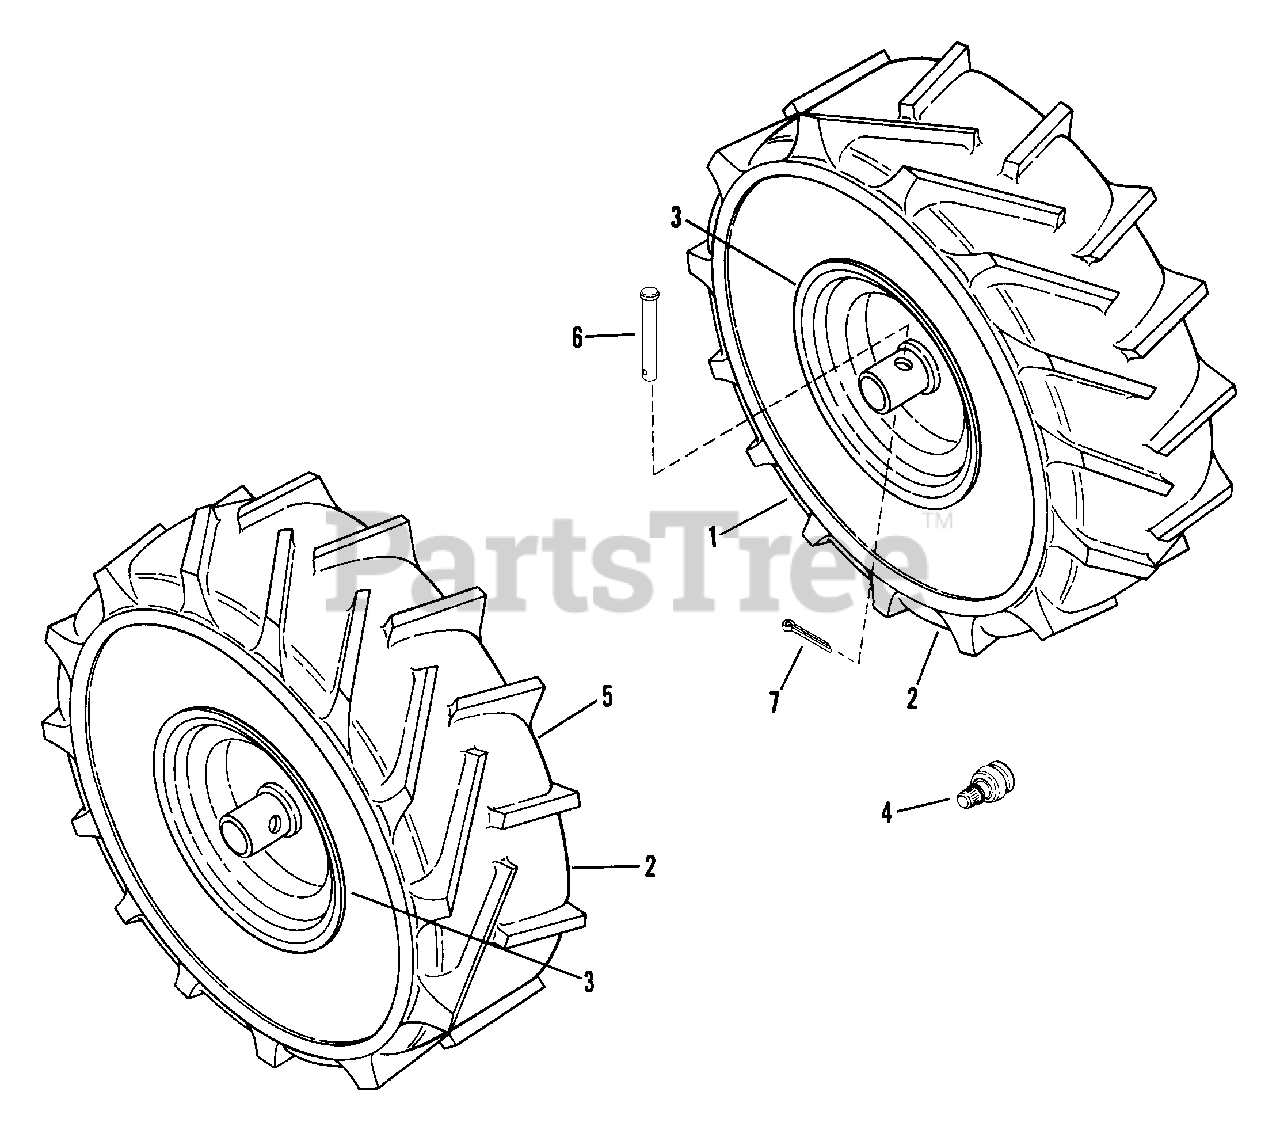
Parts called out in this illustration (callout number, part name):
1	ASSEMBLY, Right Wheel
2	TIRE, 13x5.00x6 (Lug)
4	VALVE, Air (Snap-in)
5	ASSEMBLY, Left Wheel
6	PIN 5/16x1-11/16" Clevis
7	PIN, 3/32x3/4" Cotter
